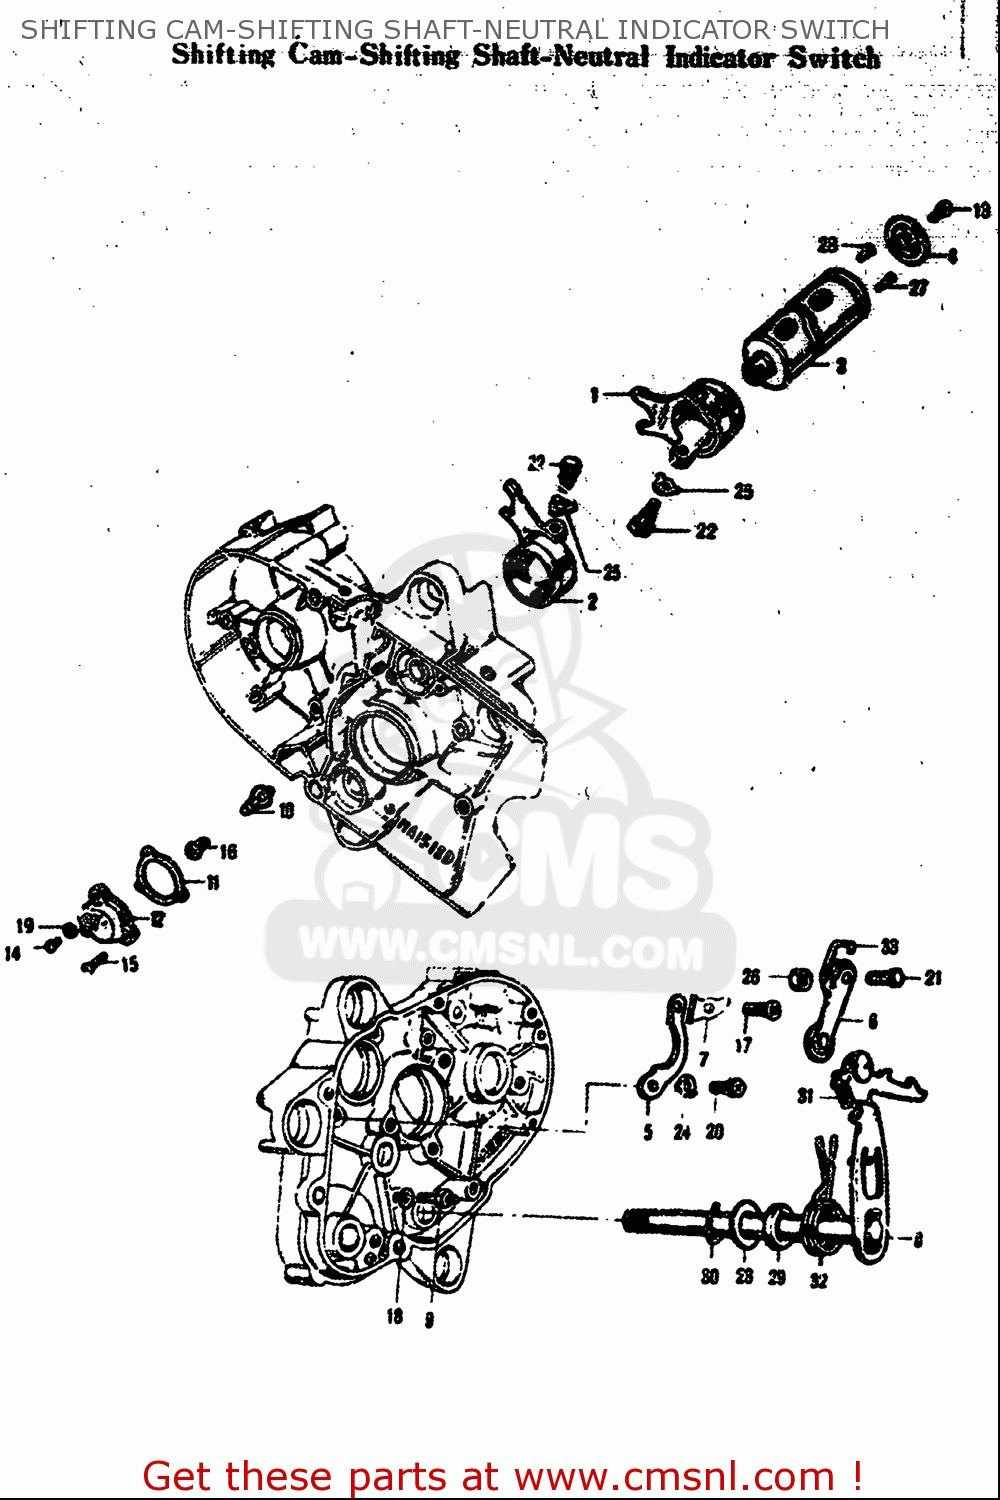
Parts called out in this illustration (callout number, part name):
10	CONTACT,GEAR SHIFT SWITCH
11	GASKET,GEAR SHIFT SWITCH (NAS)
12	BODY,CHANGE SWITCH
15	SCREW 4X16
17	SCREW
18	WASHER,LOCK
19	WASHER
23	WASHER (12.5X26X1.6)
29	SEAL,OIL (12X22X9)
30	CIRCLIP,12 MM
